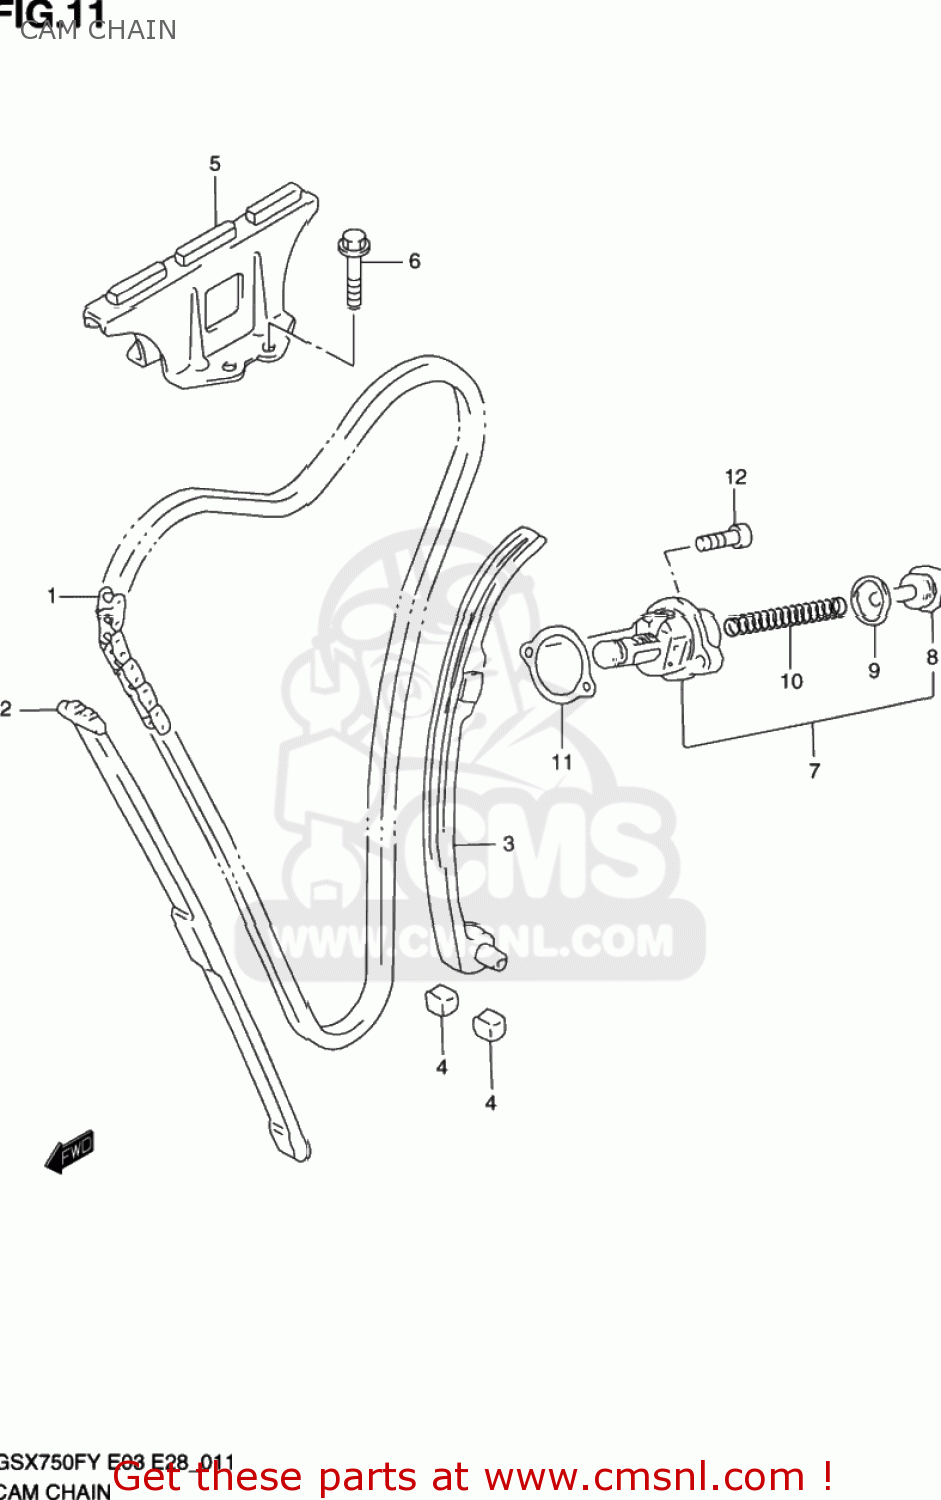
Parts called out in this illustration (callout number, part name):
1	CHAIN,CAMSHAFT DRIVE
2	GUIDE,CAM CHAIN NO.1
3	TENSIONER,CAM CHAIN
4	CUSHION,CAM CHAIN TENSIONER
5	GUIDE,CAM CHAIN NO.2
6	BOLT
7	ADJUSTER ASSY,TENSIONER
8	PLUG
9	GASKET (NAS)
10	SPRING
11	GASKET,TENSIONER ADJUSTER (NAS)
12	BOLT,CL.COVER
